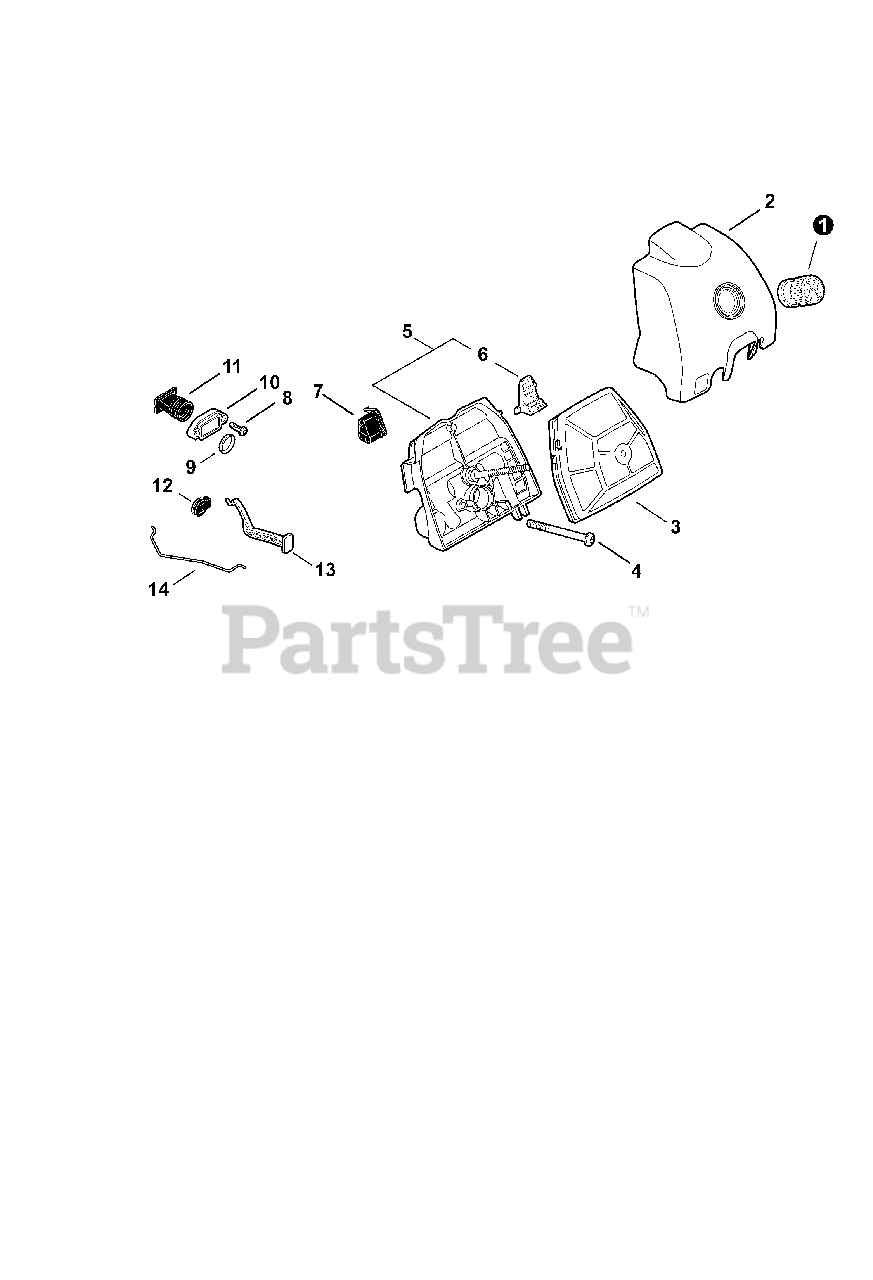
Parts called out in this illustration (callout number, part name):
1	KNOB,CLEANER LID
2	LID,CLEANER
3	ELEMENT,AIR FILTER
4	BOLT, TORX 5
5	CASE,CLEANER
6	SHUTTER, AIR
7	GROMMET,NEEDLE
8	BOLT, TORX 5
9	COLLAR,18
10	HOLDER, BELLOWS
11	BELLOWS, INTAKE
12	GROMMET,CHOKE
13	KNOB, CHOKE
14	ROD, THROTTLE
